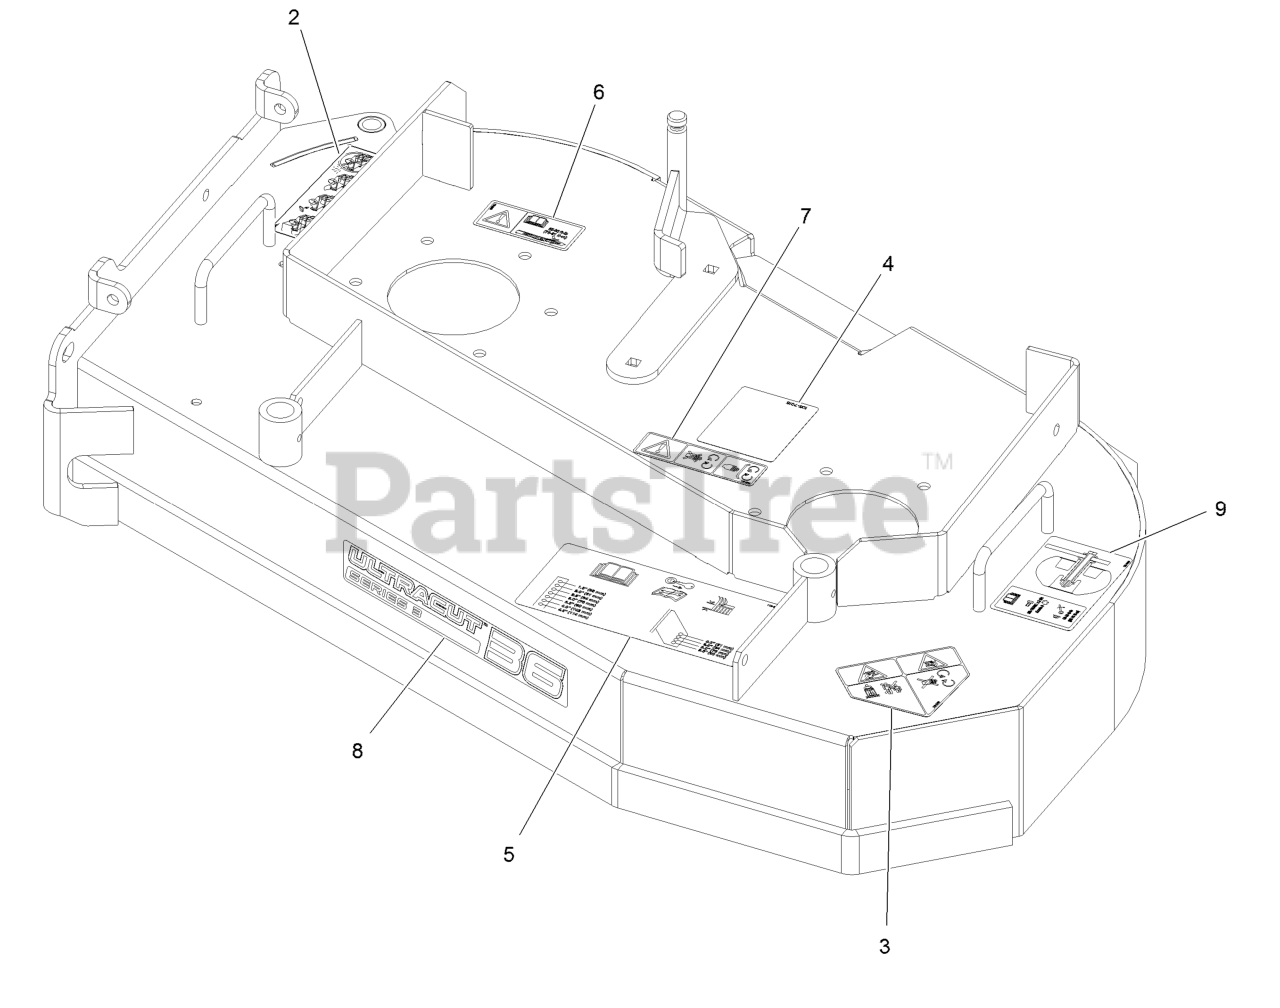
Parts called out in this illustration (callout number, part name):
2	Decal-Warning, Bagger
3	Decal-Danger
4	Decal-Routing, Belt
5	Decal-Anti-Scalp
6	Decal-Bolt Torque
7	Decal-Cover, Missing
8	Decal-Ultracut 36 Series 3
9	Decal-Roller Mounting
